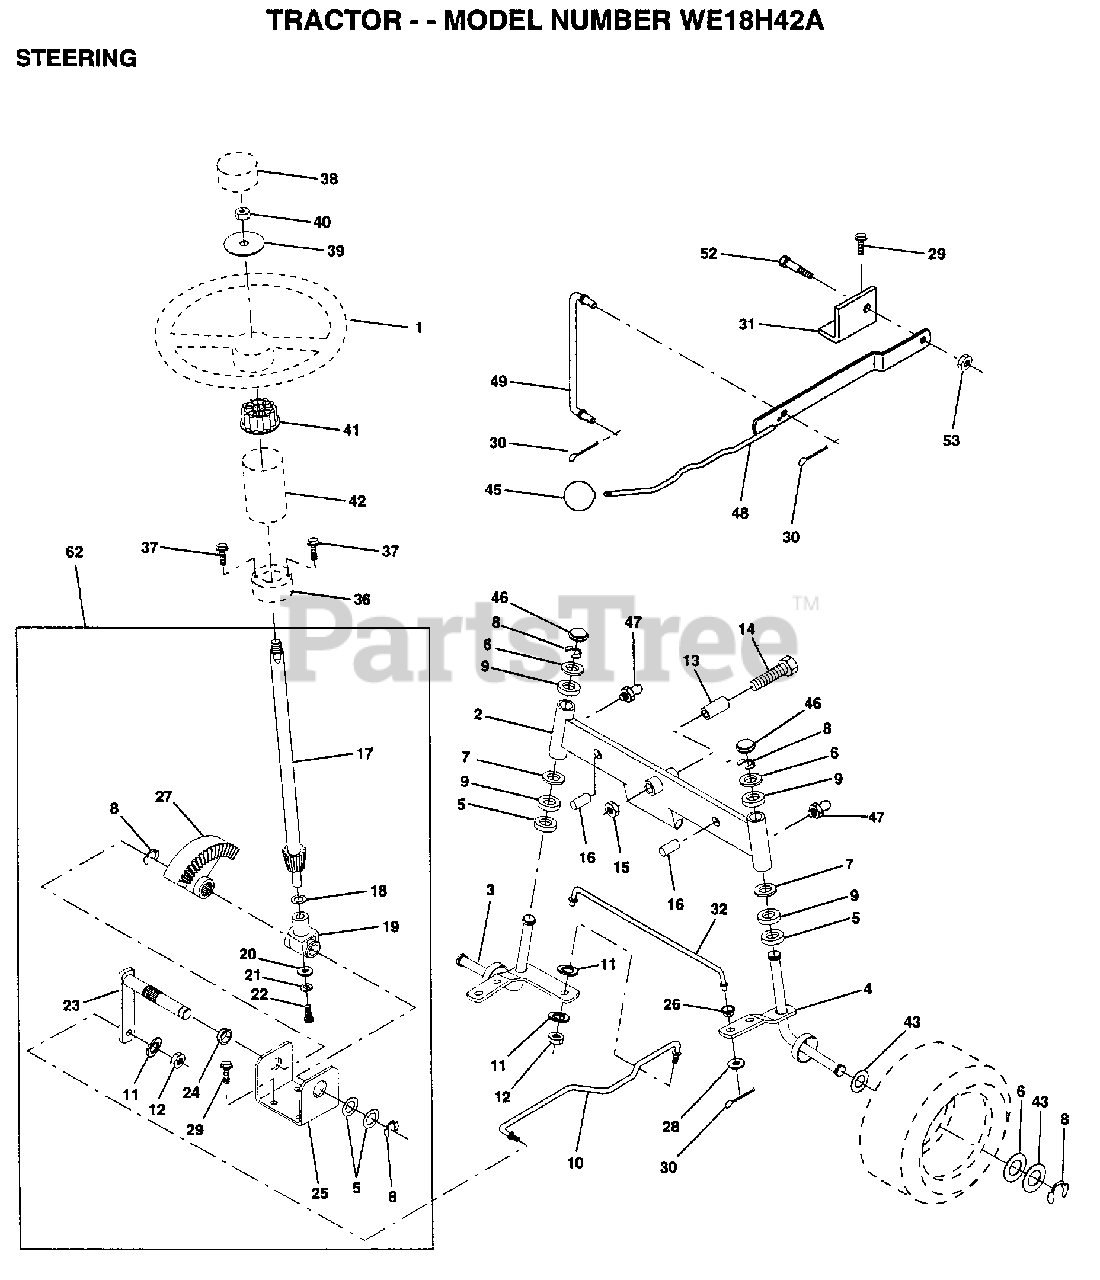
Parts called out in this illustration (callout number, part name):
2	AXLE ASM FRONT
3	SPINDLE LH
4	SPINDLE RH
5	WASHER .T
6	WASHER
7	WASHER
8	RING
9	COL. SRTG. BEAR.
11	LOCKWASHER
13	BEARING
14	BOLT HEX 5/8-11
15	"NUT-LOC,FLANGE LT"
16	AXLE PIN
17	STEERING SHAFT
18	THRUST WASHER
19	SUPPORT.SHAFT
21	LOCKWASHER
22	"SCREW,SPECIAL"
24	NYLINER T
25	"BRKT,STEERING"
26	BUSHING.DRAGLINK
27	GEAR SECTOR
28	WASHER
29	SCREW
30	COTTER PIN
31	BRKT.PVT.MAN.LVR.
32	TIE ROD
36	BUSHING.STRG.3/4
37	SCREW.10-24X1/2
38	ST WHL INSERT CAP
39	WASHER
41	ADAPTER LT
42	BOOT SHAFT STEER
43	WASHER
45	KNOB T (1/2-HOLE)
46	CAP
47	ZERK M
48	LEVER.ASM.CLUTCH
49	LINK CLTCH W/NUTS
52	"BOLT, SHOULDER LT"
